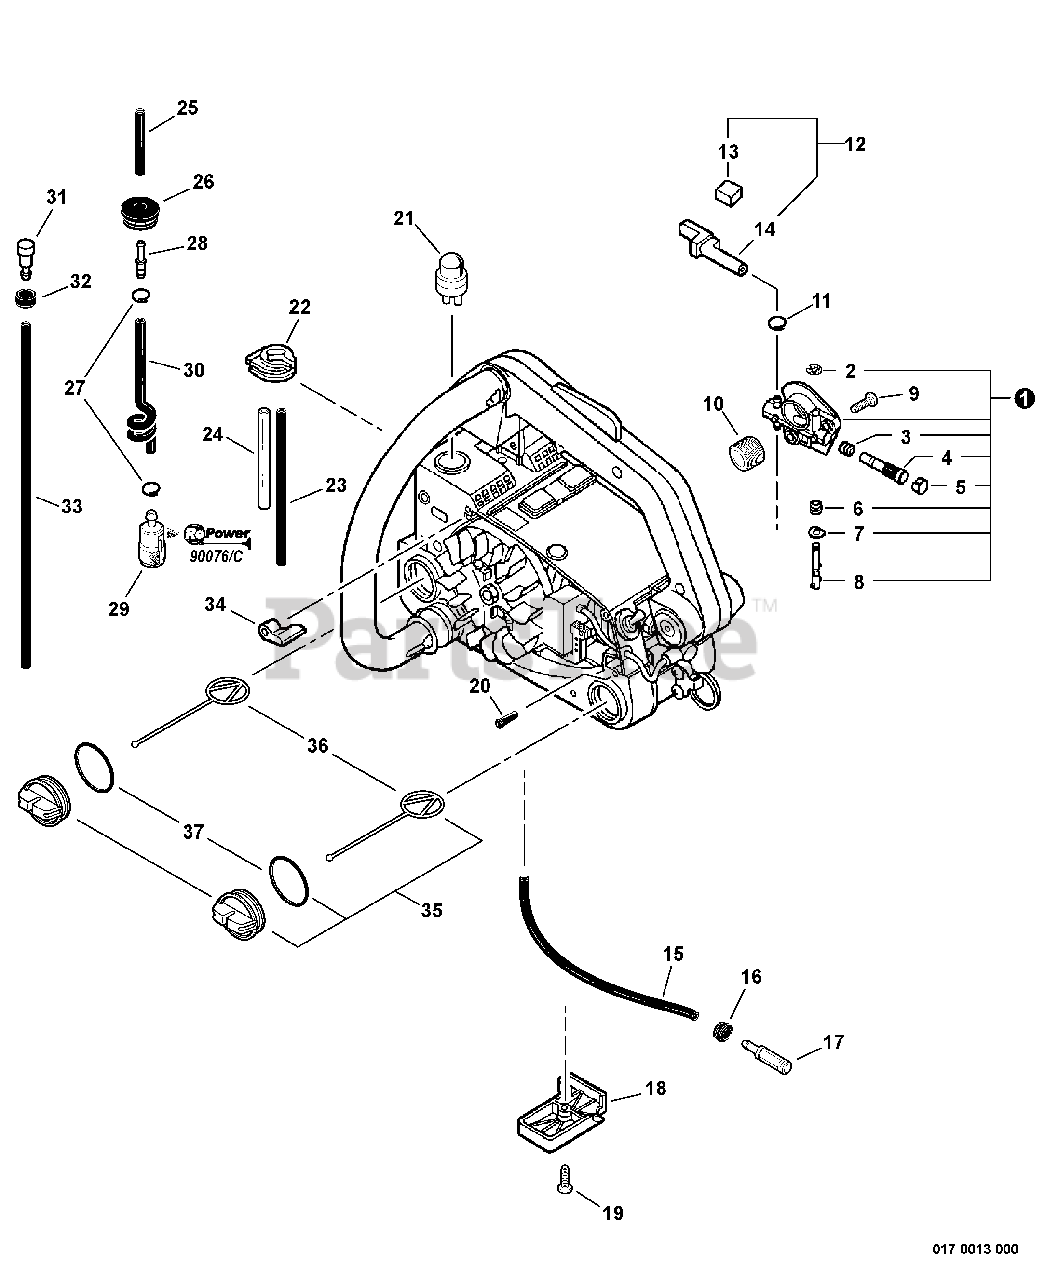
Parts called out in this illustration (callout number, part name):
1	AUTO-OILER ASSY
2	RING, RETAINING
3	SPRING, PLUNGER
4	PLUNGER ASSY
5	CAP, OIL PUMP
8	NEEDLE, ADJUST
9	SCREW - 5X12
10	GEAR - WORM
11	CLIP - 6.5
12	OIL PIPE KIT
13	PAD, FOAM
14	PIPE - OIL
15	PIPE - 3X6X115 -- BLACK
16	GROMMET
17	FILTER, OIL
18	COVER, BOTTOM - ORANGE
19	SCREW - 4X16
20	VENT, TANK
21	PUMP, PURGE
23	PIPE - 3X5X70 -- BLACK
24	PIPE - 2X4X42 -- CLEAR
25	PIPE - 3X6X36 -- BLACK
26	GROMMET
27	CLIP - 6.5
28	CONNECTOR, PIPE
29	FILTER, FUEL
30	PIPE, FUEL - SPIRAL
31	VENT, FUEL TANK
32	HOLDER, VENT
33	PIPE - 3X5X150 -- BLACK
35	CAP ASSY - BLACK
36	CONNECTOR, CAP
37	O-RING - 25
38	RePower TUNE-UP KIT
